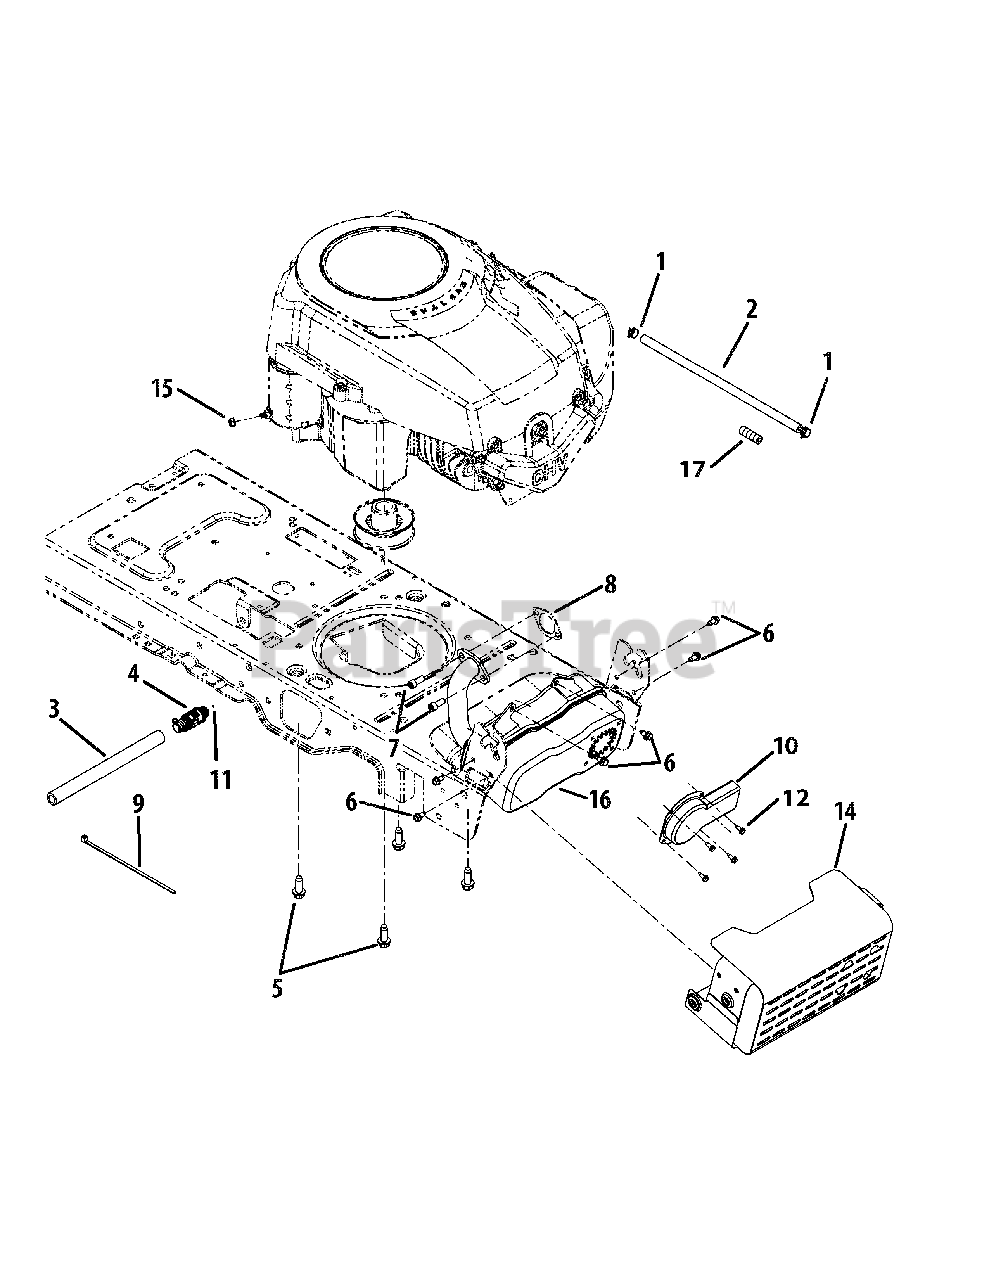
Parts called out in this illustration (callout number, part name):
1	Hose Clamp
2	Fuel Line 16" Lg.
3	Oil Drain Hose
4	Oil Drain
5	TT Screw 3/8-16 x 1.00
6	Hex Wash S-Tapp Screw 1/4-20 x .50
7	Screw. 5/16-18 x .75
8	Exhaust Gasket
9	Cable Tie
10	Long Muffler Deflector
11	Pipe Sealant (puchase locally)
12	Hex AB Screw #8-18 x .50
14	Muffler Shield Assembly
15	Hex Sems Nut 1/4-20
16	Muffler
17	Vent Hose (optional)
